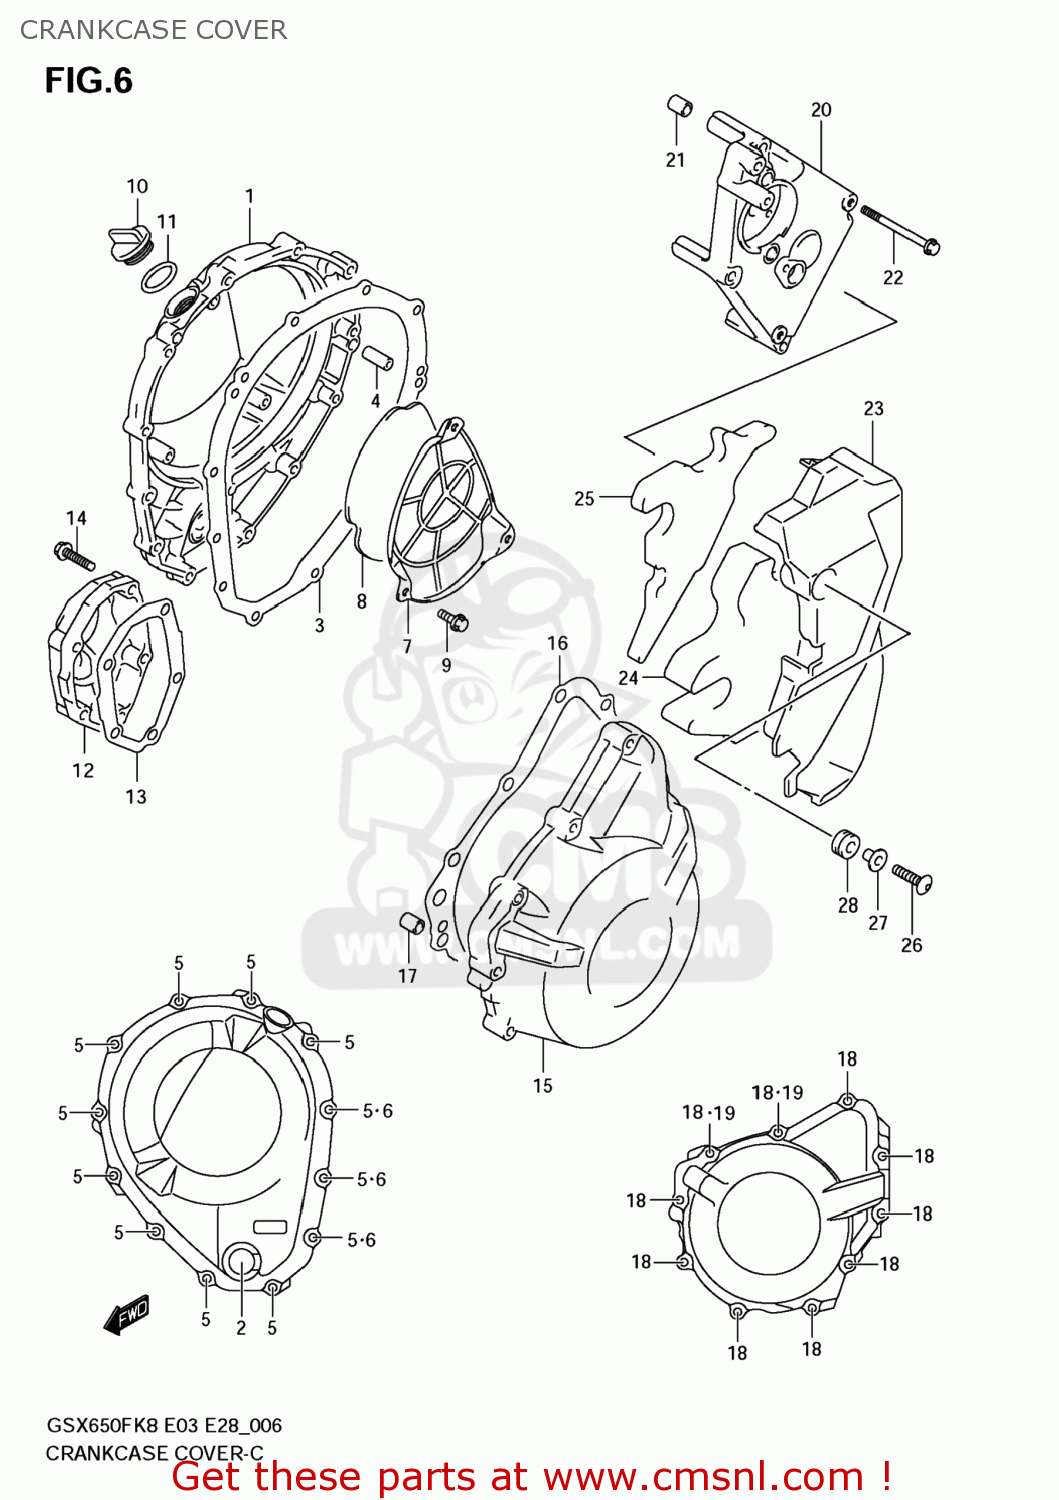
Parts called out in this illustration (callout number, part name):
1	COVER,CLUTCH
2	LENS,OIL LEVEL CHECK
3	GASKET,CL COVER (NAS)
4	PIN
5	BOLT(6X30)
6	GASKET(5.8X13X1.2) (NAS)
7	PLATE,CLUTCH COVER
8	DAMPER,CLUTCH COVER
9	BOLT
10	PLUG,ENGINE OIL FILLER
11	O RING(D:3.1,ID:16.8)
12	COVER,CRANKSHAFT,R
13	GASKET,CRANKSHAFT,R COVER (NAS)
14	BOLT(6X30)
15	COVER,MAGNETO
16	GASKET,MAGNETO COVER (NAS)
17	PIN
18	BOLT(6X30)
19	GASKET(5.8X13X1.2) (NAS)
20	COVER,ENGINE SPROCKET INNER
21	PIN
22	BOLT
23	COVER,ENGINE SPROCKET OUTER
24	CUSHION,ENG SPRKT COVER NO.1
25	CUSHION,ENG SPRKT COVER NO.2
26	SCREW(6X20)
27	WASHER
28	CUSHION
